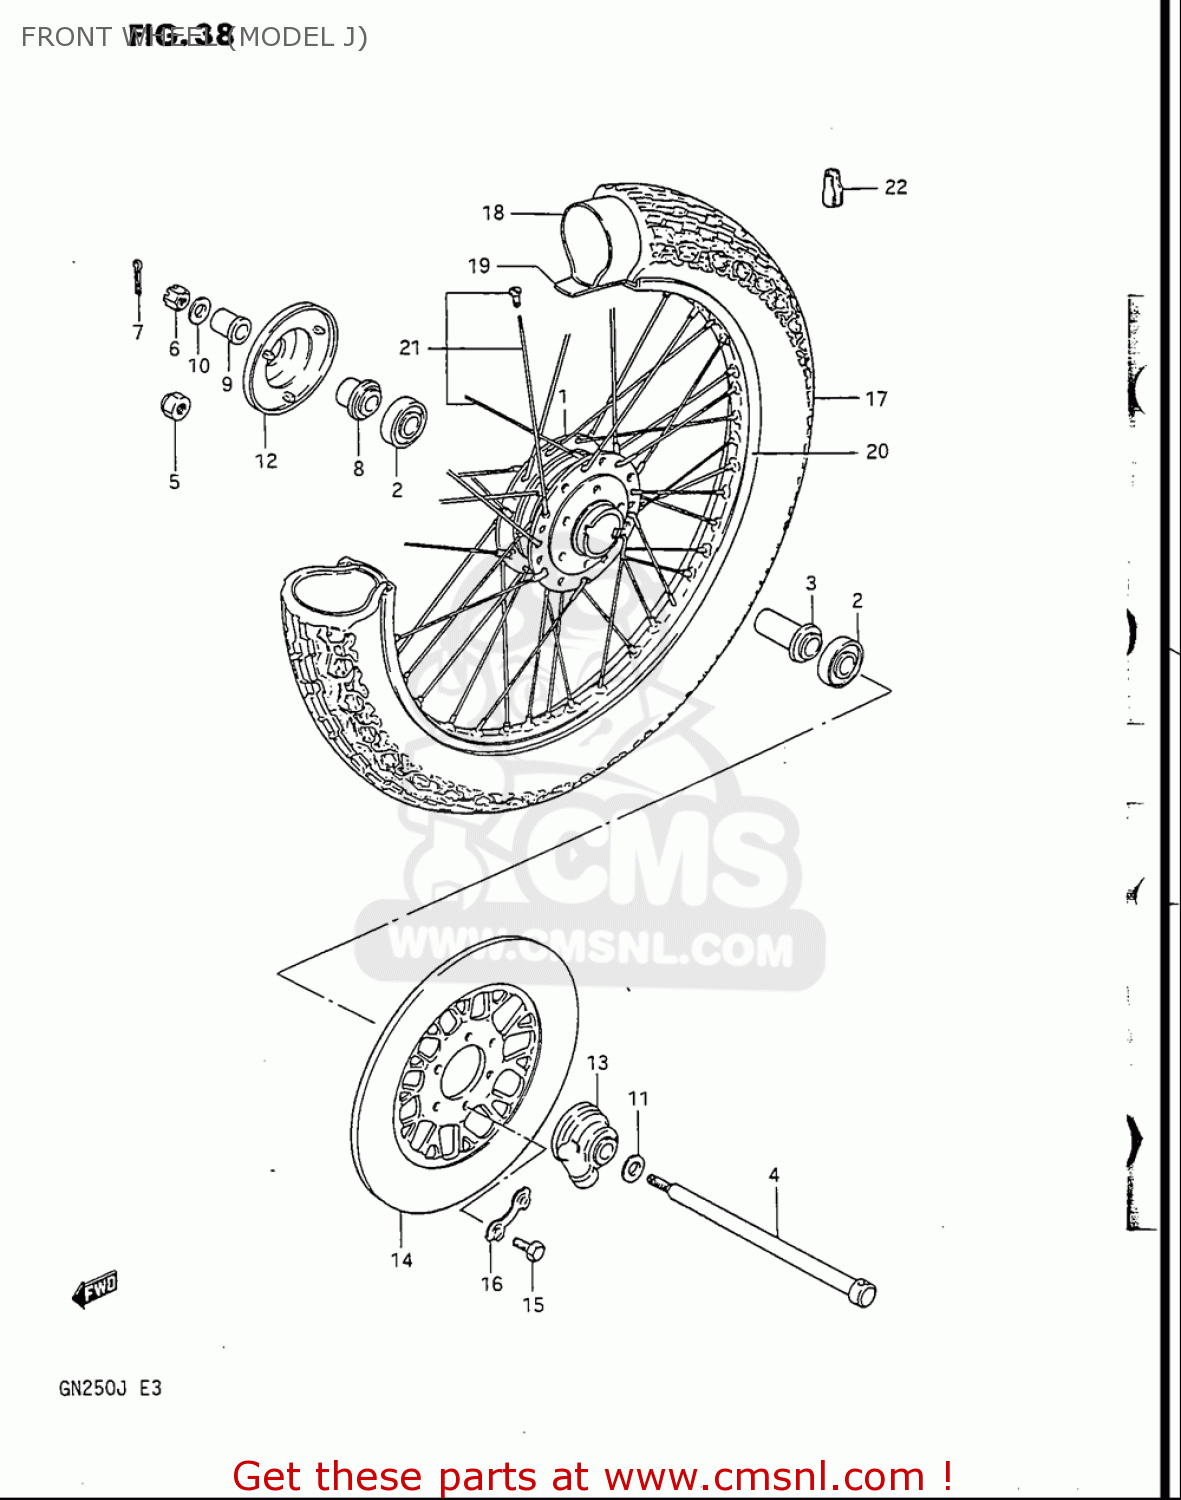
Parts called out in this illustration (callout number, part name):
1	HUB,FRONT WHEEL
3	SPACER,FR HUB BEARING
4	AXLE,FR
5	NUT
6	NUT 12MM
7	PIN
8	SPACER,FR AXLE,R
9	SPACER
10	WASHER
11	WASHER(15.5X26X2.3)
12	COVER,FR HUB,R
13	BOX ASSY,SPEEDOMETER GEAR
14	DISC,FR BRAKE
15	BOLT(8X25)
16	WASHER
17	TIRE,FRONT 3.00 S18
18	TUBE ASSY,WHEEL INNER
19	PROTECTOR,INNER TUBE
20	RIM,FR WHEEL
21	SPOKE ASSY,FR WHEEL
22	BALANCER,WHEEL (B)
